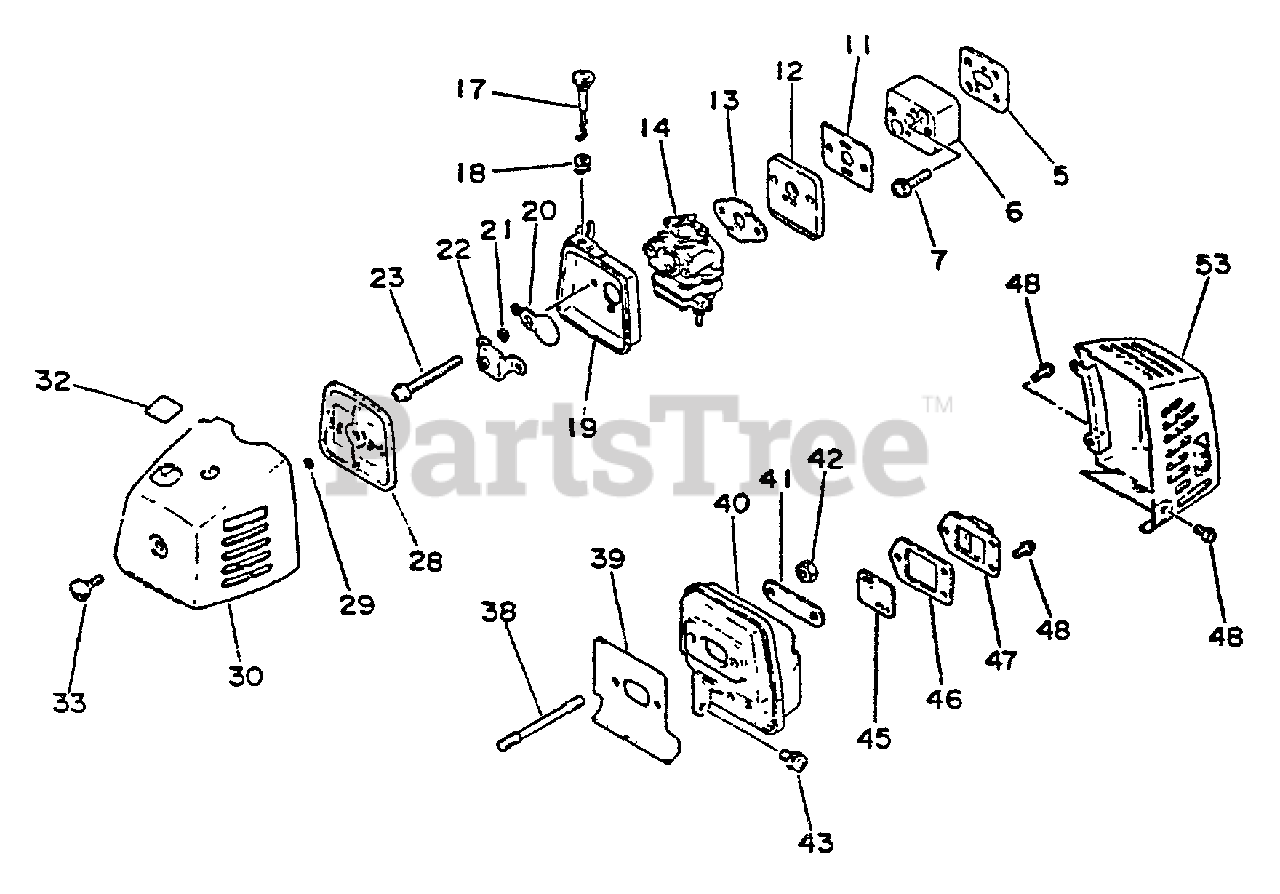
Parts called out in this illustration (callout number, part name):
5	GASKET, INTAKE
6	INSULATOR
7	SCREW 5×22
11	GASKET, INTAKE
12	PLATE
13	GASKET, INTAKE
14	CARBURETOR
17	ROD, CHOKE
18	GROMMET, CHOKE
19	CASE, AIR FILTER
20	SHUTTER, CHOKE
21	WASHER 5.2×8×0.8T
22	PLATE, PREVENT
23	SCREW 5×50
28	FILTER, AIR
30	AIR FILTER COVER ASSY
32	LABEL, CHOKE
32	LABEL - CHOKE
38	BOLT, STUD
39	GASKET, EXHAUST
40	MUFFLER
42	LOCKNUT - 5
43	SCREW - 5×10
45	SCREEN, SPARK ARRESTER
46	GASKET, EXHAUST
47	GUIDE, EXHAUST
48	SCREW 4×8
53	COVER, MUFFLER
